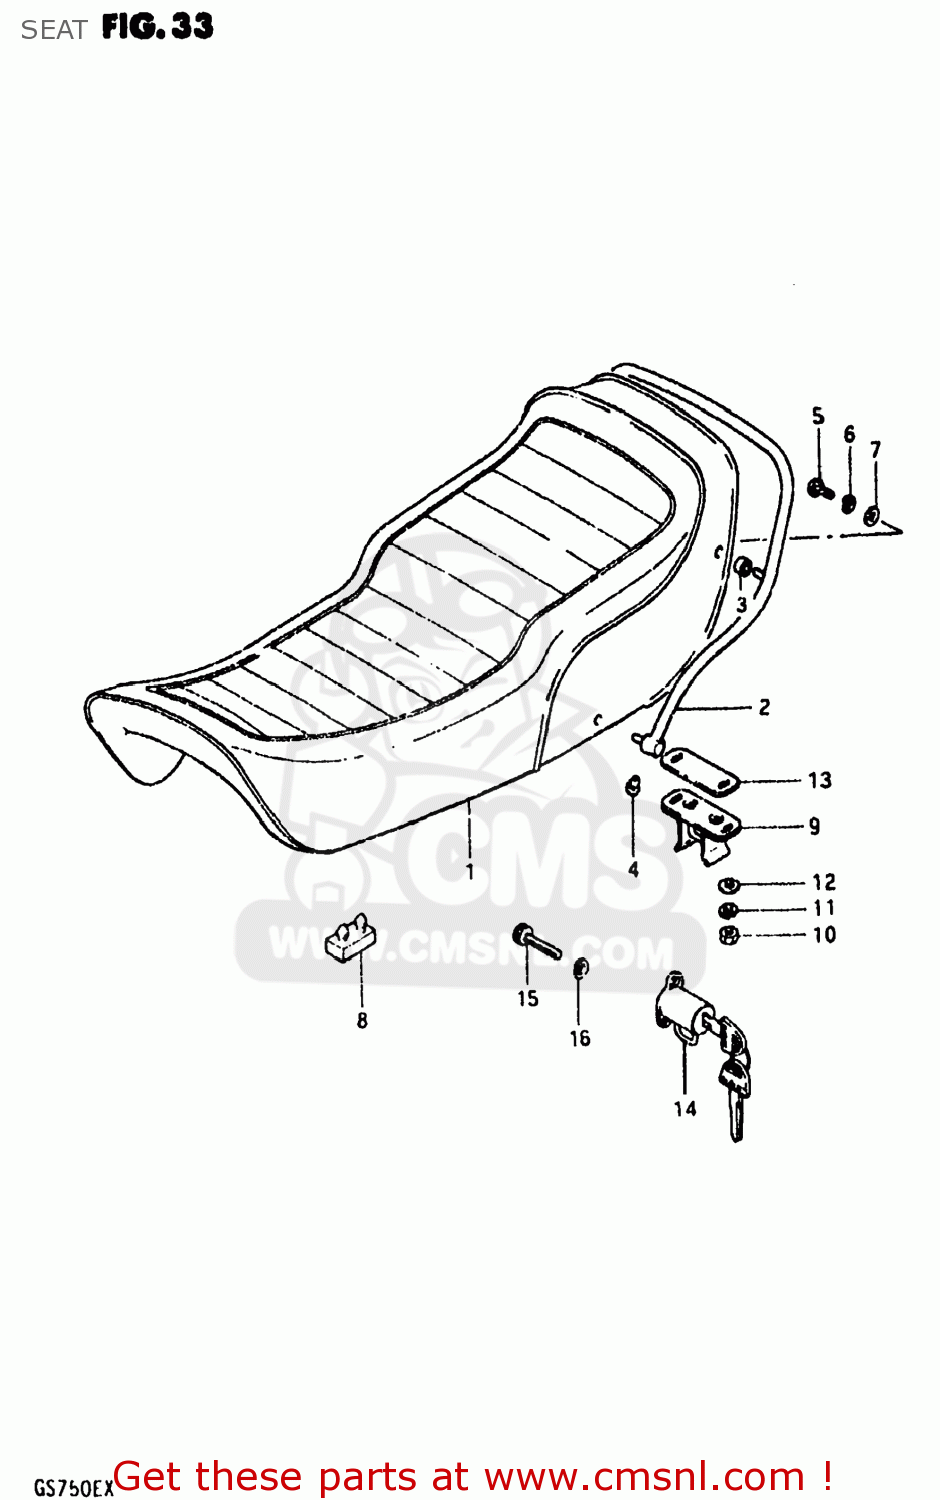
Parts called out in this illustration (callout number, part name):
1	SEAT ASSEMBLY
2	HANDLE,PILLION RIDER
3	CUSHION
4	END,SHEET HANDLE
5	BOLT
6	LOCK WASHER
7	WASHER
8	CUSHION
9	STRIKER, SEAT LOCK
10	NUT 6MM
11	LOCK WASHER
12	WASHER
13	SHIM,SEAT LOCK STRIKER
14	LOCK ASSEMBLY,HELMET
15	BOLT
16	LOCK WASHER
